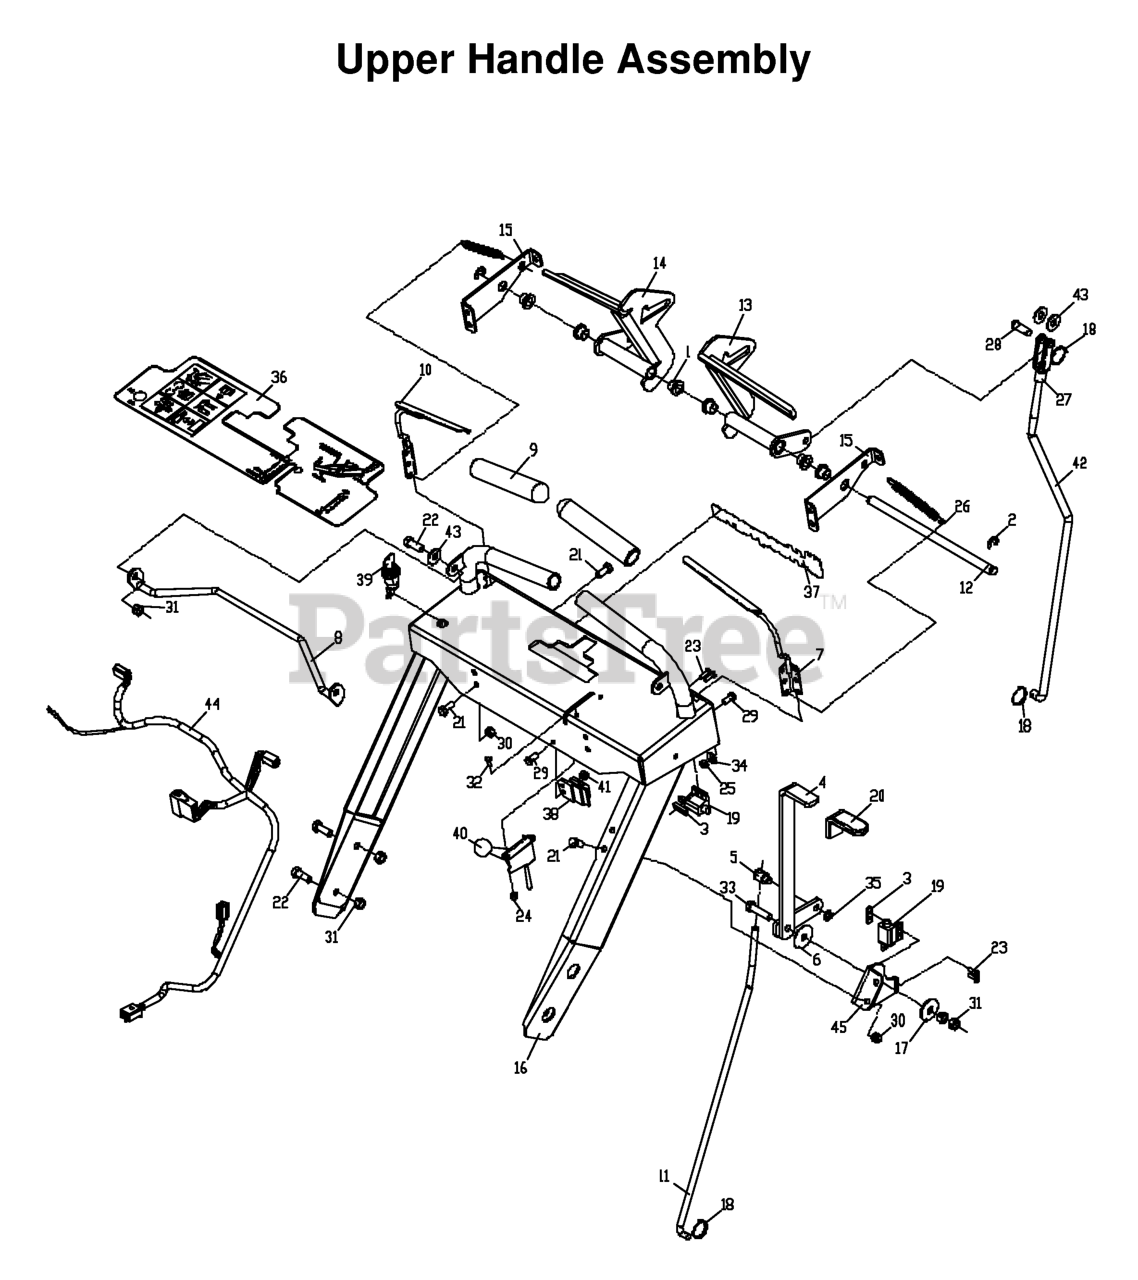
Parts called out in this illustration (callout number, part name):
1	BUSHING, FLANGED NYLON
2	E-RING 1/2 (2 2)
3	TAPPED PLATE
4	ENGAGEMENT LEVER
6	WASHER, FRICTION
7	OPER LEVER-LH
8	NEUTRAL BAIL
10	OPER LEVER - RH
11	BLADE ENGAGE LINK
12	CENTER PIVOT SHAFT
13	DRIVE LEVER - LH
14	DRIVE LEVER - RH
15	SUPPORT BRACKET
16	HANDLE WELDMENT
17	CONE WASHER
21	HCS 5/16C X 3/4
22	HCS 3/8-16X1.GRD.5.ZD
23	SCREW #10-24 X 5/8
24	NUT 10-24 NYLOC
25	NUT 1/4C CENTER LOCK
27	YOKE-3/8-24 PLTD
28	CLEVIS PIN 3/8 X 1 1/8
29	HCS 1/4C X 5/8
30	NUT 5/16C CENTERLOCK
31	NUT 3/8C CENTERBLOCK
32	HCS #10-24 X 1/2
33	HCS 3/8C X 1 1/2
34	WASHER 1/4 FLAT
35	E RING 3/8"
36	CONSOLE DECAL
37	DECAL, HUSQ 15" BLUE
39	KEY SWITCH, COMPLETE
40	THROTTLE CONTROL W/BALL KNOB
41	NUT.1/4-20.HEX.NYLOC.ZD
42	DRIVE LINKAGE
43	WASHER 3/8 FLAT
44	UPPER HARNESS
45	BLADE ENGAGEMENT BRK
46	TIE, PLASTIC
